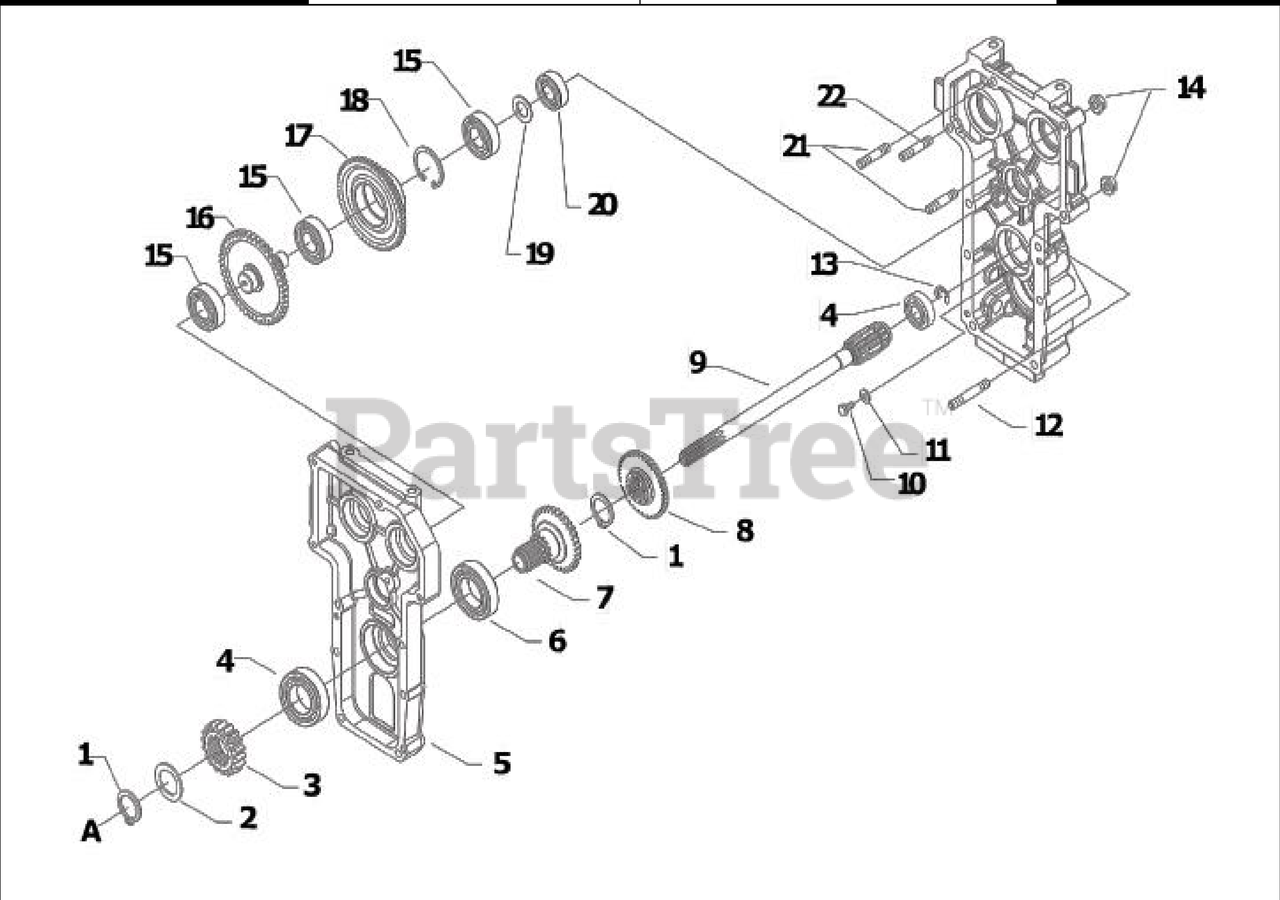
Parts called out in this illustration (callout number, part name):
1	SNAP RING E 20 UNI 7436
2	WASHER
3	IDLER GEAR
4	BEARING 6005 (25X47X12)
5	HYDRO FLANGE
6	BEARING 6006 (30X55X13) SKF
7	DEFLECTION SHAFT
8	OUTPUT GEAR
9	PRIMARY CLUTCH SHAFT
10	SCREW TE M10X20 UNI 5739
12	STUD BOLT M8X56X20X14
13	SNAP RING E 15 UNI 7434
14	SELFLOCK NUT M8 6S
15	BEARING 6004 (20X42X12)
16	IDLE PUMP GEAR
17	IDLE ENGINE GEAR
18	RING
19	WASHER
20	BEARING 6202 (15X35X11)
21	STUD BOLT M8X56X20X14
22	STUD M8X40X14X20 8G
